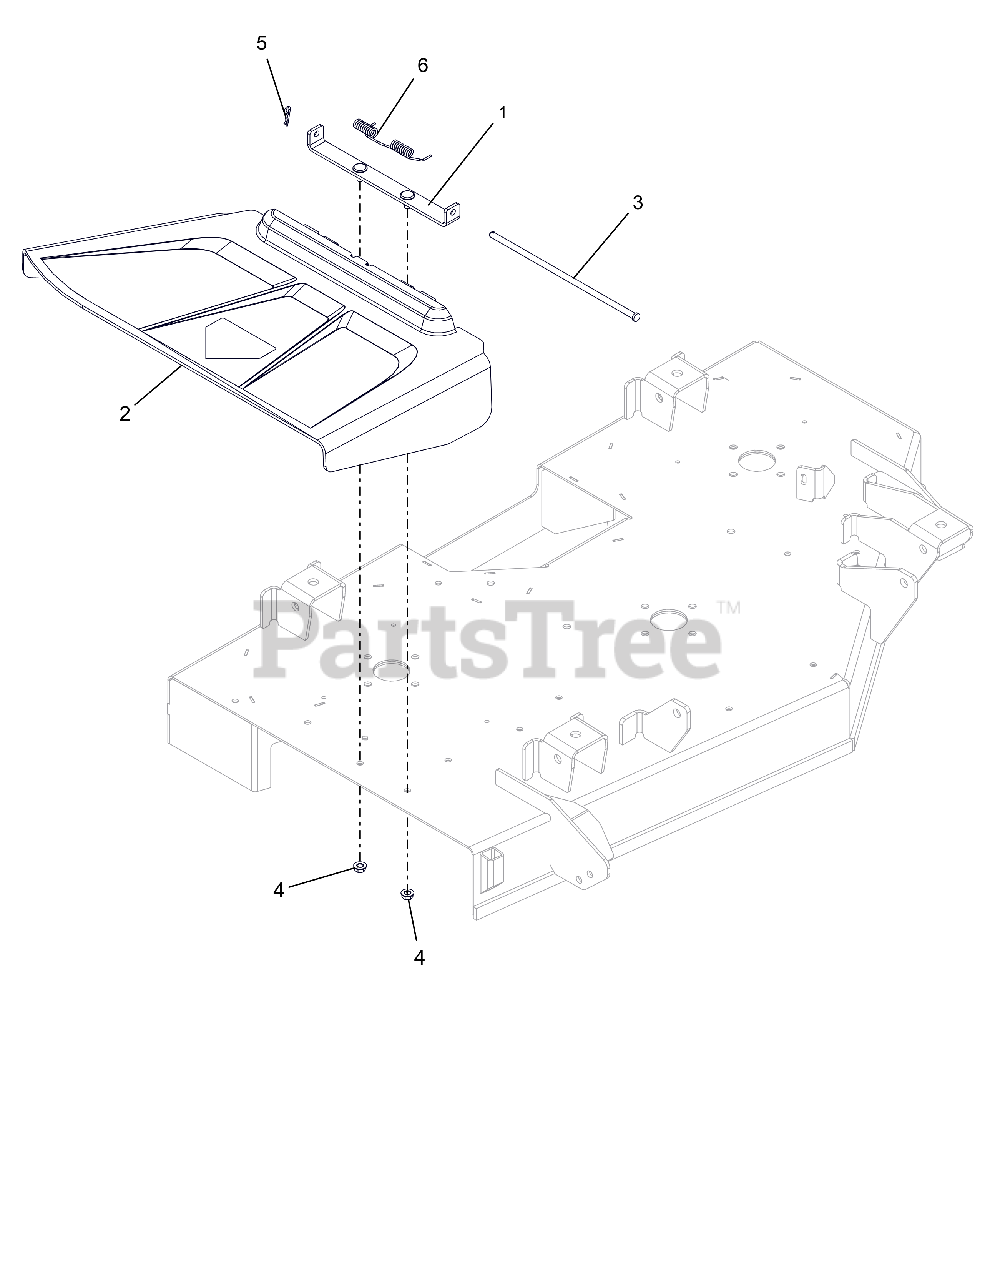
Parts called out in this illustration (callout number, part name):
1	WLDMT, CHUTE MT BRKT
2	CHUTE, SIDE DISCHARGE
3	PIN, 5/16 X 10.5
4	@NUT-LK-TOP-FLG .31-18 YWZC
5	PIN-HAIR INT .08X.18X1.18 YWZC
6	SPRING-TORSION
